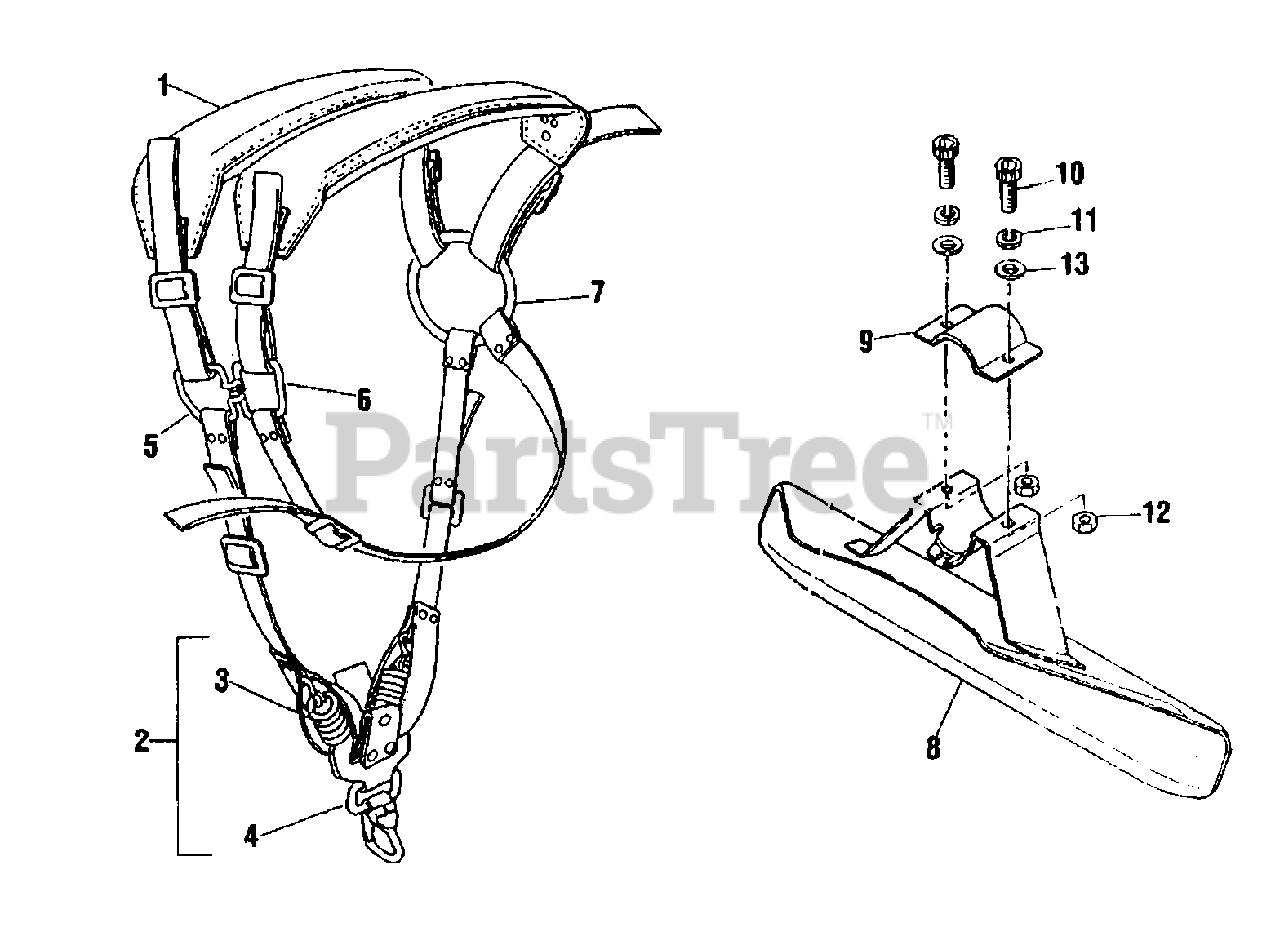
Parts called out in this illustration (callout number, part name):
1	PROTECTOR
2	HOLDER
3	SPRING
4	HOOK
5	CHEST LATCH (A)
6	CHEST LATCH (B)
7	RING
8	GUARD
9	GUARD, CLAMP
10	BOLT 5×16
11	WASHER, SPRING 5
12	NUT M5
13	WASHER, FLAT 5.5×10×0.8
